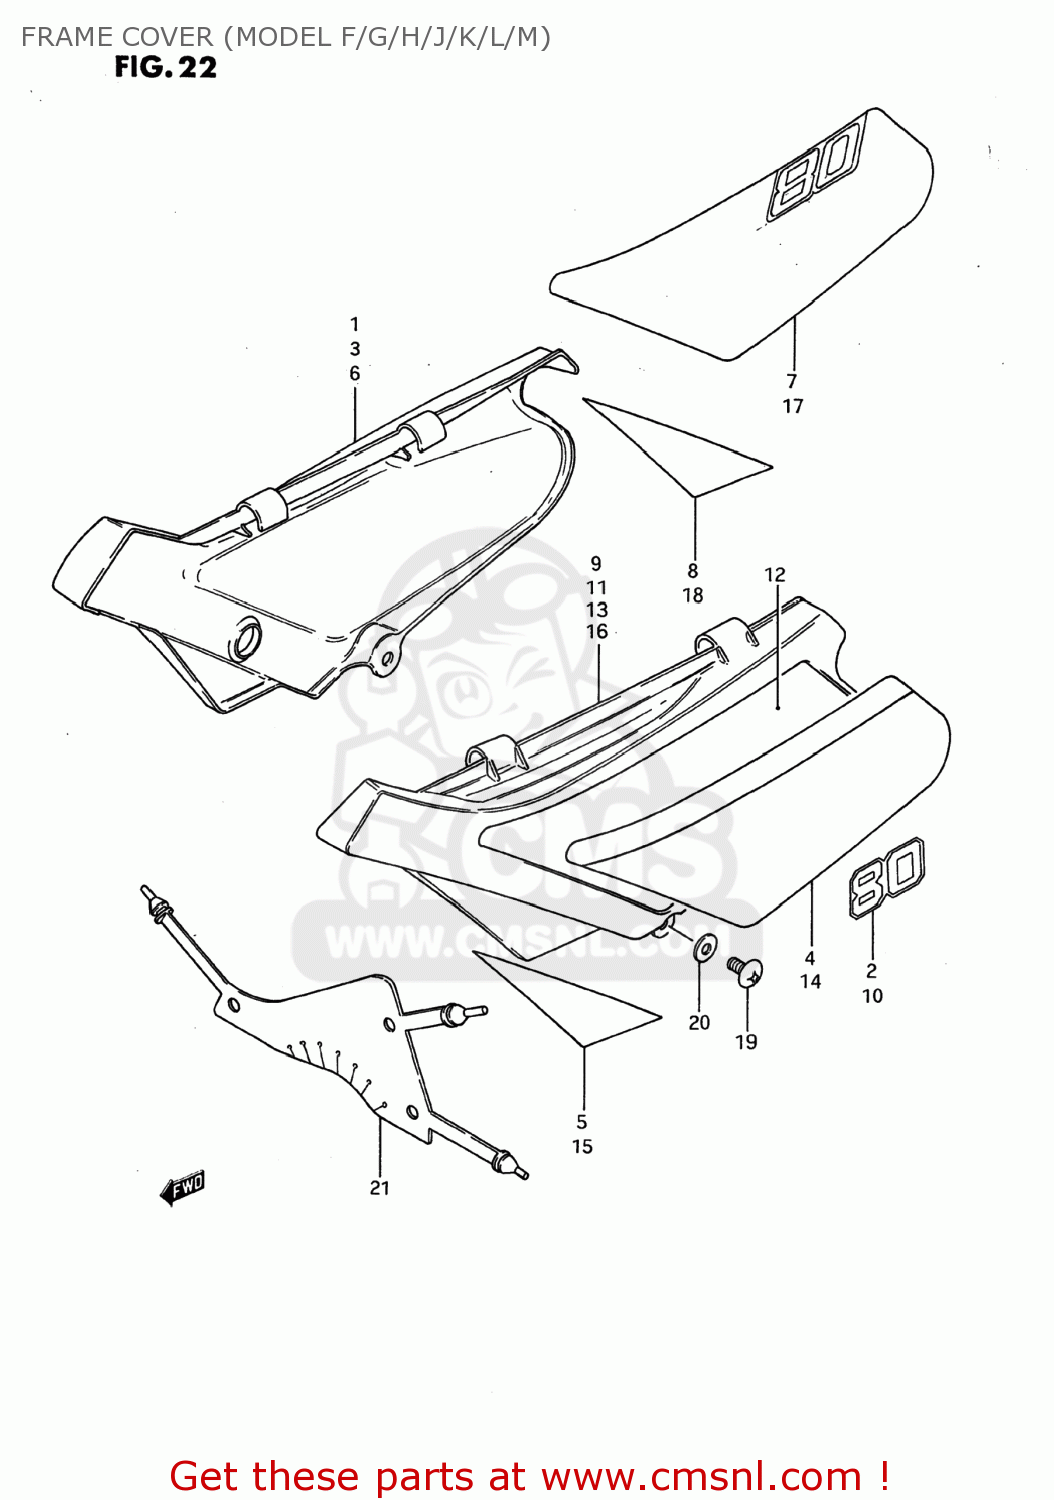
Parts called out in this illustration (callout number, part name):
1	COVER,FRAME,RIGHT
2	EMBLEM,FRAME COVER RH
3	COVER,FRAME,RIGHT
4	TAPE,FRAME COVER,RIGHT
5	TAPE,RIGHT NO.2
6	COVER,FRAME,RIGHT
7	TAPE,FRAME COVER,RIGHT
8	TAPE,FRAME COVER NO.2,R
9	COVER,FRAME,LEFT
10	EMBLEM,FRAME COVER,LEFT
11	COVER,FRAME,LEFT
12	EMBLEM,FRAME COVER,LEFT
13	COVER,FRAME,LEFT
14	TAPE,FRAME COVER
15	TAPE,LEFT NO.2
16	COVER,FRAME,LEFT
17	TAPE,FRAME COVER
18	TAPE,FRAME COVER NO.2
19	SCREW
20	WASHER(6.5X16X1.2)
21	MUD GUARD,FRAME COVER
